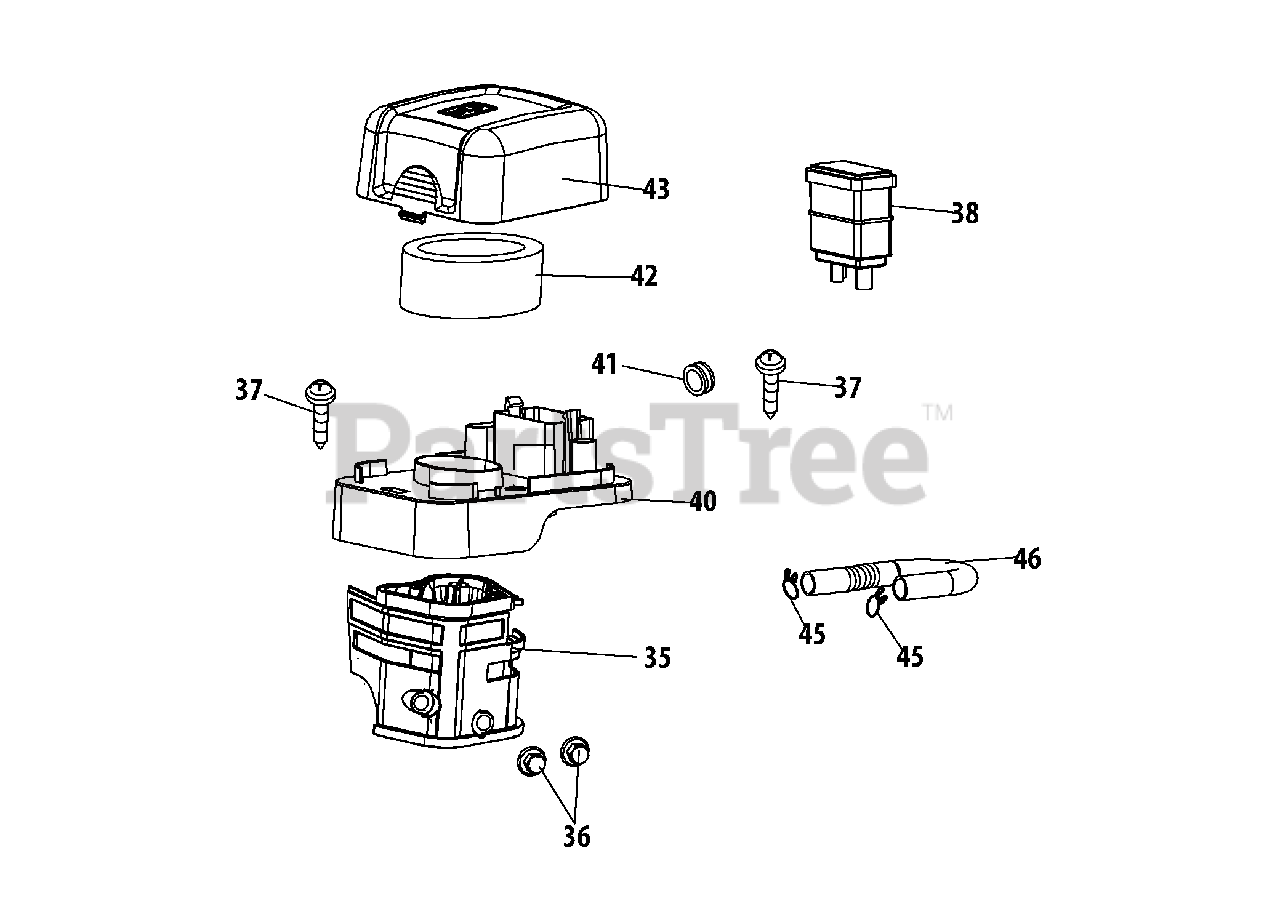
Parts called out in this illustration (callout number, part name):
35	Air Cleaner Housing
37	Self-Tapping Bolt4.2×16
38	Carbon Canister
40	Silencer Plate
42	Air Filter
43	Air Cleaner Cover
45	Piping Hose
46	Exhaust Piping
